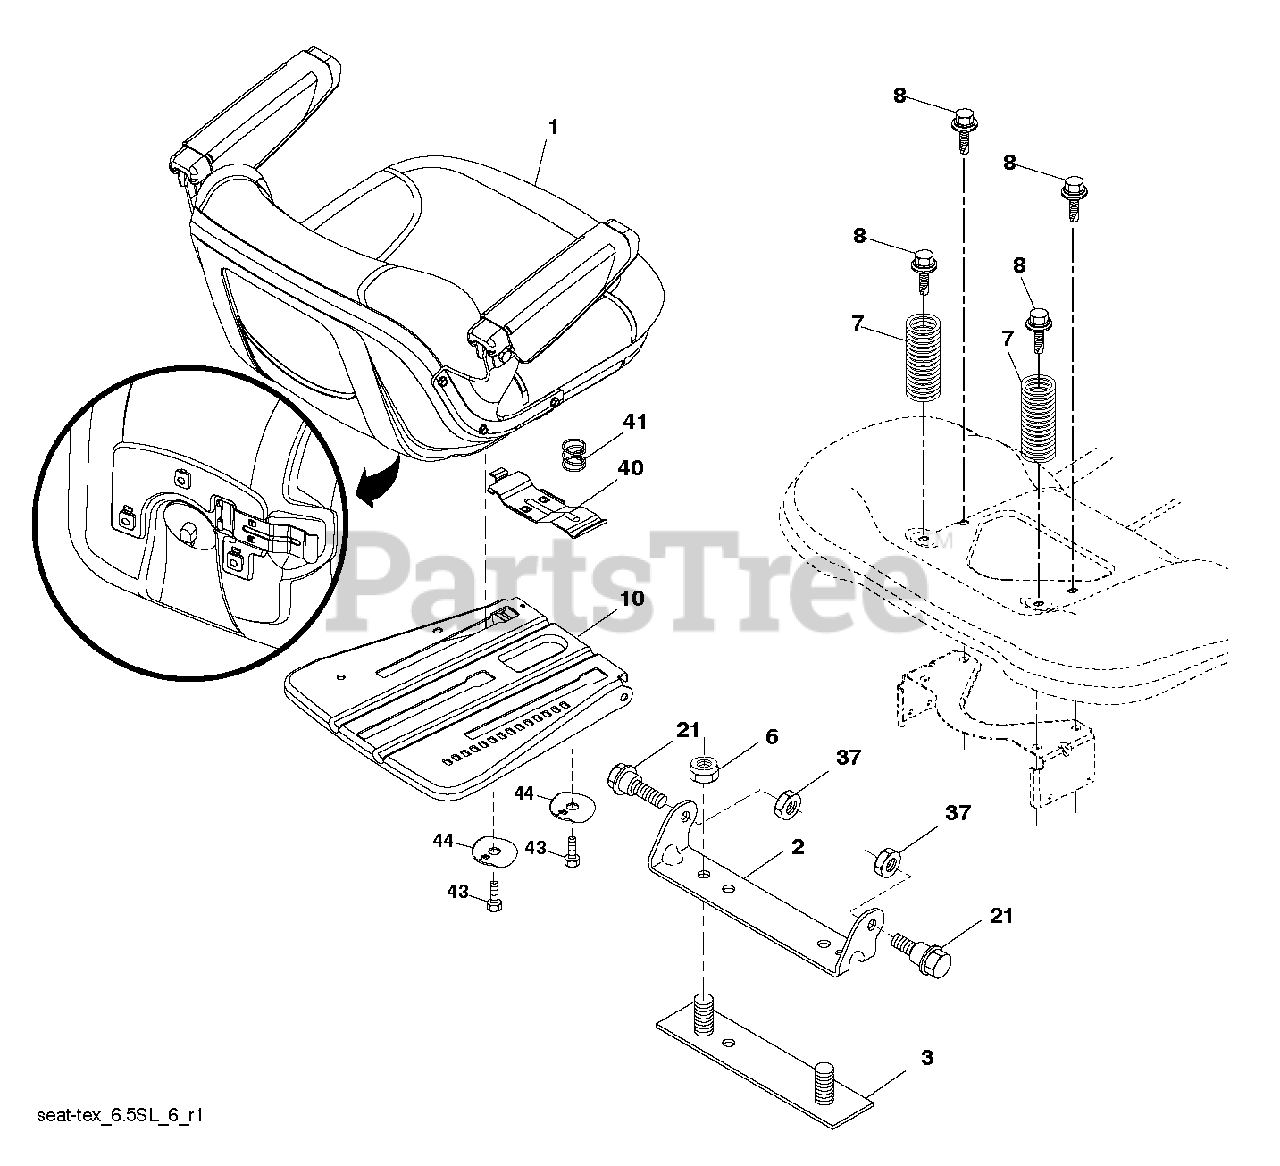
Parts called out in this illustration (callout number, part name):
1	SEAT.TH154.498GY.HUS.
2	BRKT.PIVOT.FENDER
3	STRAP
6	NUT
7	SPRING.COMPRESS.SEAT.
8	BOLT, 5/16-18 X 1 3/4
10	Seat Slide Plate, Pnt
21	BOLT.5/16-18X5/8.SHOULDER
37	NUT.71038.31-18.HEX.NYLOCK
40	HANDLE.SLIDE.SEAT.TEX.BLACK
41	SPRING.LATCH.SEAT.TEX
44	Winged Washer, 38Id 1
